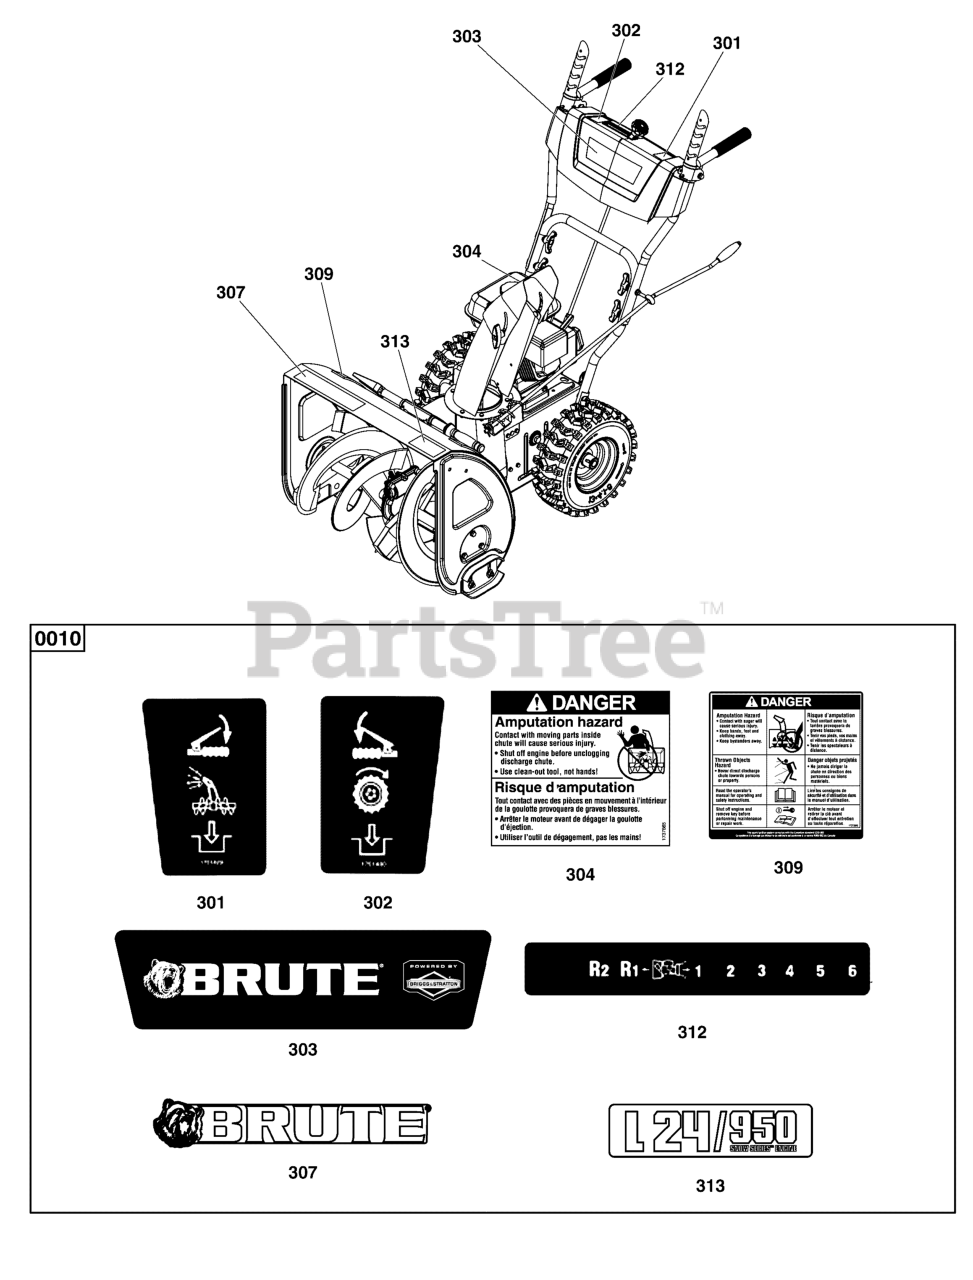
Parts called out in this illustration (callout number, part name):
0010	KIT-DECAL
301	DECAL, Auger Control
302	DECAL, Traction Control
303	*DECAL, Control Panel, Brute
304	DECAL, Danger Chute Warning, FR/ENG
307	DECAL, Auger Housing, Brute
309	DECAL, Danger Foot, FR/ENG
312	DECAL, 1-6 Transmission Speed Control
